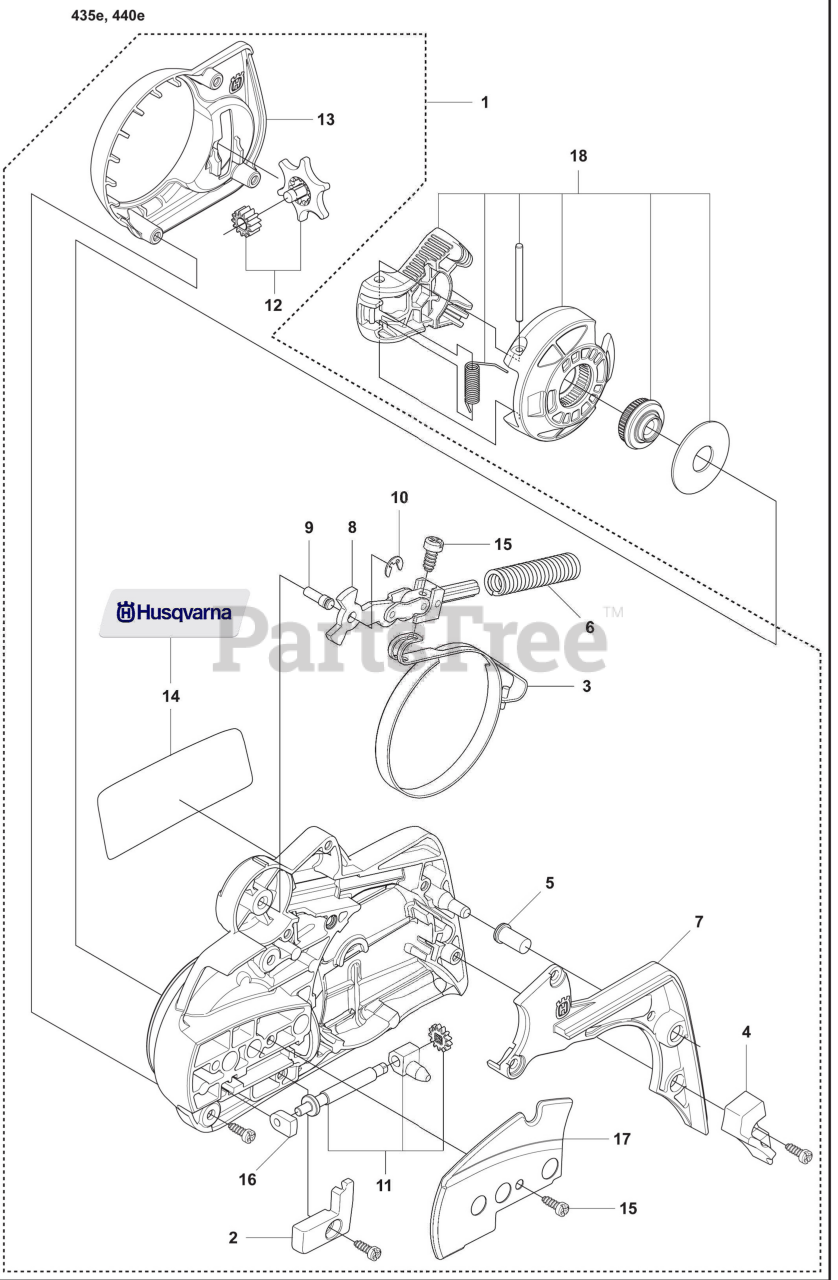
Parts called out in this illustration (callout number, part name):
1	Chain Brake Assembly, Husq Orange
2	Cover
3	Brake Band Assembly
4	Wear Protection
5	Sleeve
6	RP BLADE GUARD
7	Cover
8	Joint
9	Pin
10	Bar Retainer
11	Chain Tensioner Screw, Comp
12	Chain Tensioner Wheel
13	Heat Shield
14	Clutch Housing Decal
15	Screw
16	Sleeve Bearing
17	Plate
18	Complete Knob
